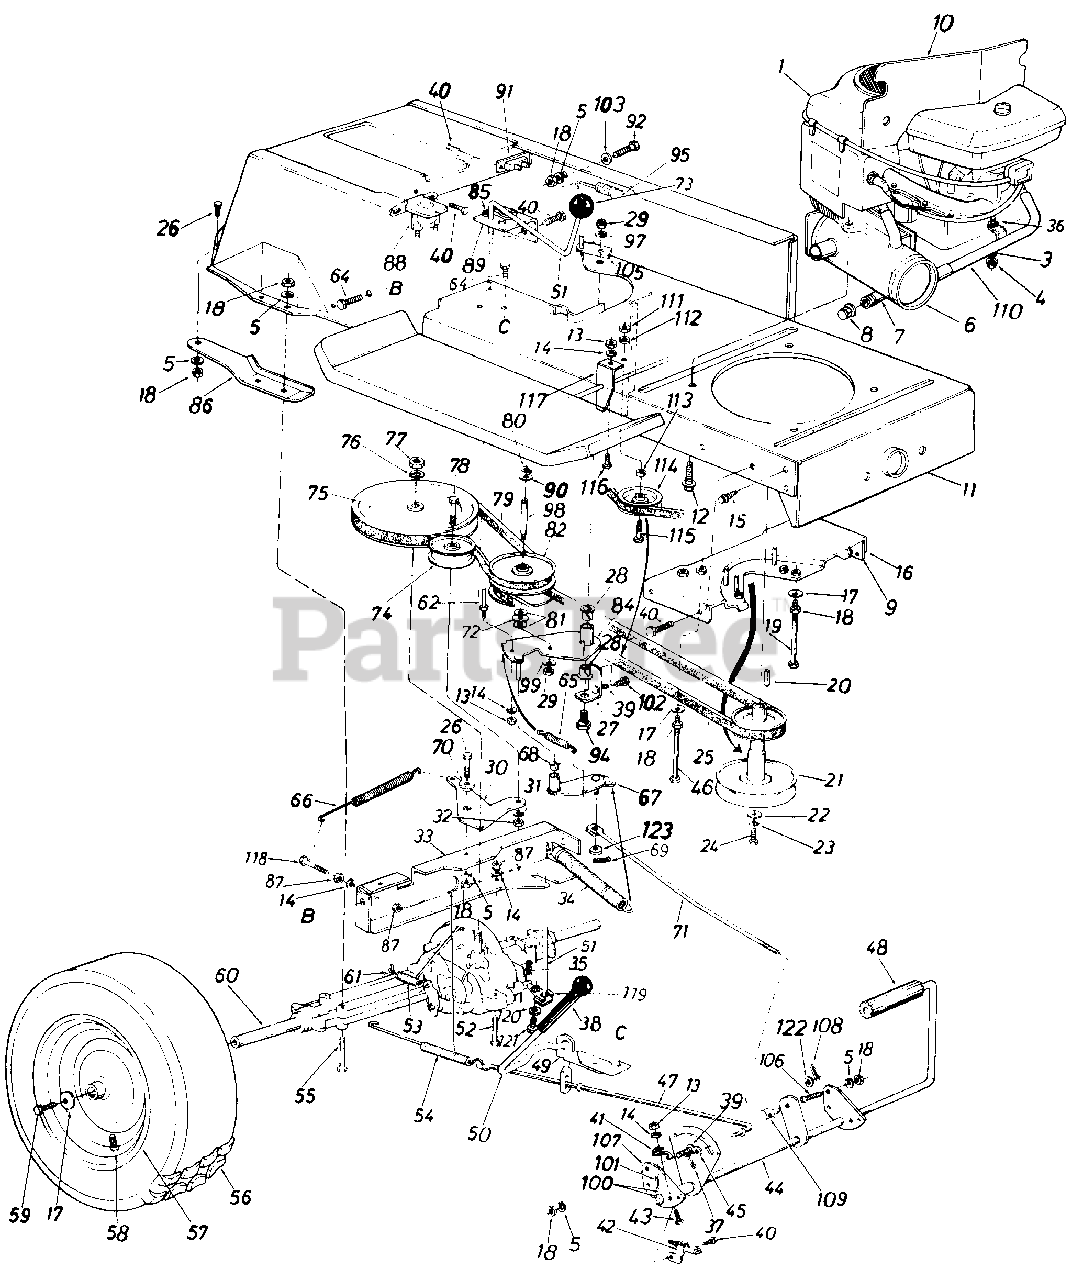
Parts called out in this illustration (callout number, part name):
1	Engine
3	Special L-Wash. 5/16" I.D.
4	Hex Nut 5/16-18 Thd.*
5	L-Wash. 5/16" I.D.*
6	Exhaust Muffler
7	Pipe Nipple
8	Cap Oil Drain
9	Brake Cable Brk't.
10	Heat Shield
11	Lower Frame Ass'y.
12	Hex Wash. Hd. TT-Tap Scr. 3/8-16 x 1.25" Lg.
13	Hex Nut 1/4-20 Thd.*
14	L-Wash. 1/4" I.D.*
15	Hex Wash. Hd. AB-Tap Scr. 5116" x.75" Lg.
16	Belt Guard Brkt. Ass'y.
17	Bell-Wash. .345" I.D. x .88"
18	Hex Nut 5/16-18 Thd.*
19	Hex Bolt 5/16-18 x 4.00"*
20	Sq. Key 1/4" x 1/4" x 2.00"
21	Engine Pulley
22	Fl-Wash. 7/16" I.D. x 1.25"
23	L-Wash. 7/16" I.D.*
24	Hex Bolt 7/16-20 x 1.50" Lg.
25	Variable-Speed Belt
26	Hex Bolt 5/16-18 x .75" Lg.*
27	Bearing Shaft Bracket Ass'y.
28	Flanged Nyliner Brg. 518" I.D. x .88" Lg.
29	Hex Nut 3/8-24 Thd.*
30	Idler Bracket
31	L-Wash. 3/8" I.D.*
32	Hex Nut 3/8-24 Thd.*
33	Transaxle Support Brkt.
34	Ext. Spring .94" O.D. x 6.7
35	Inter. Cotter Pin
36	Fl-Wash. .34" I.D. x .62" O.D. x .033
37	Cotter Pin 3/32" Dia. x .75"*
38	Grip-Black
39	Truss Mach. Scr. 5/16-18 x .75" Lg.
40	Hex Wash. Hd. Self-Tap Scr. 1/4-20 x .50" Lg.
41	Switch Actuator
42	Safety Switch
43	Hex Bolt 1/4-20 x 1.0" Lg.*
44	Clutch & Brake Pedal Ass'y.
45	Fl-Wash.
46	Hex Bolt 5/16-18 x 4.5"*
47	Brake Rod 20.9" Lg.
48	Foot Pad
49	Brake Lever Bracket
50	Hill Holder Brake Handle
51	Shift Lever Ass'y.
52	Hex Bolt 1/4-28 x 1.75" Lg.
53	Ext. Spring x 2.5" Lg.
54	Ext. Spring x 7.08" Lg.
55	Hex Bolt 5/16-18 x 2.75"
57	Wheel Rim Only
58	Air Valve
59	Hex Bolt 5/16-24 x .75" Lg.
60	Transaxle Complete-R.H.
61	Brake Return Spring Anchor
62	Belt Guard Pin 1/4-20 Thd.
64	Hex Wash. TT-Tap Scr. 5/16 x .62" Lg.
65	Ext. Spring
66	Ext. Spring .62" O.D. x 6.12"
67	Variable Speed Torque Brkt. Ass'y.
68	Flanged Bearing
69	Cotter Pin 3/32" Dia.
70	Shoulder Spacer .500" Dia. x.27" Lg.
71	Speed Control Link
72	Truss Bearing .56 Dia. x 1 .25"
73	Ball Knob
74	Fl-Idler Pulley 3.25" x .75"
75	1/2" "V"-Pulley 8.0" O.D. x .501 " I.D.
76	L-Wash. 1/2" I.D.
77	Hex Jam Nut 1/2-20 Thd.
78	Hex Bolt 3/8-24 x .75" Lg.
79	Variable-Speed Belt
80	Snap Ring .56" Dia.
81	Fl-Wash.
82	Variable Speed Pulley Ass'y. 5" O.D.
84	Variable Speed Brkt. Ass'y.
85	Comp. Spring Clip
86	Transaxle Support Brkt.-R.H.
87	Hex Nut 1/4-28 Thd.
88	Solenoid
89	Shift Lever Bracket
90	Teflon Washer
91	Circuit Breaker
92	Hex Bolt 5/16-18 x 1.50" Lg.
94	Shld. Bolt 3/8-24 x 3.12" Lg.
95	Ext. Spring .99" O.D. x 11.0"
97	Bell-Wash. .38" I.D. x .88"
98	Shaft .56" Dia. x 3.875" Lg.
99	Bell-Wash. .39" I.D. x 1.12"
100	Fl-Wash.
101	Cotter Pin 3/32" Dia. x .75"
102	Hex Wash. Hd. Scr. 5/16-18 x .62" Lg .
103	Fl-Wash. .34" I.D. x 1.12" O.D.
105	Belt Guard
106	Hex Bolt 5/16-18 x .75" Lg.
107	Pedal Bracket
108	Cotter Pin 3/32 x .75"*
109	Ferrule
110	Inlet Tube Ass'y.
111	Hex Nut 3/8"-16 Thd.
112	L-Wash. 3/8" I.D.
113	Fl-Wash. .390" I.D. x 1.12"
114	Fl-Idler w/Flanges 2.750
115	Hex Bolt 3/8-16 x 2.00" Lg.
116	Hex Bolt 1/4-20 x .62" Lg.*
117	Spring Hanger Bracket
118	Hex Bolt 1/4-28 x 1.25" Lg.
119	Shift Lever Link Ass'y.
120	Bell-Wash. .265 I.D. x .75 O.D.
121	Hex Bolt 1/4-28 x .62" Lg.
122	Fl-Wash. .385" I.D. x .62" O.D.
123	Fl-Wash. .34" I.D. x .68" O.D.
